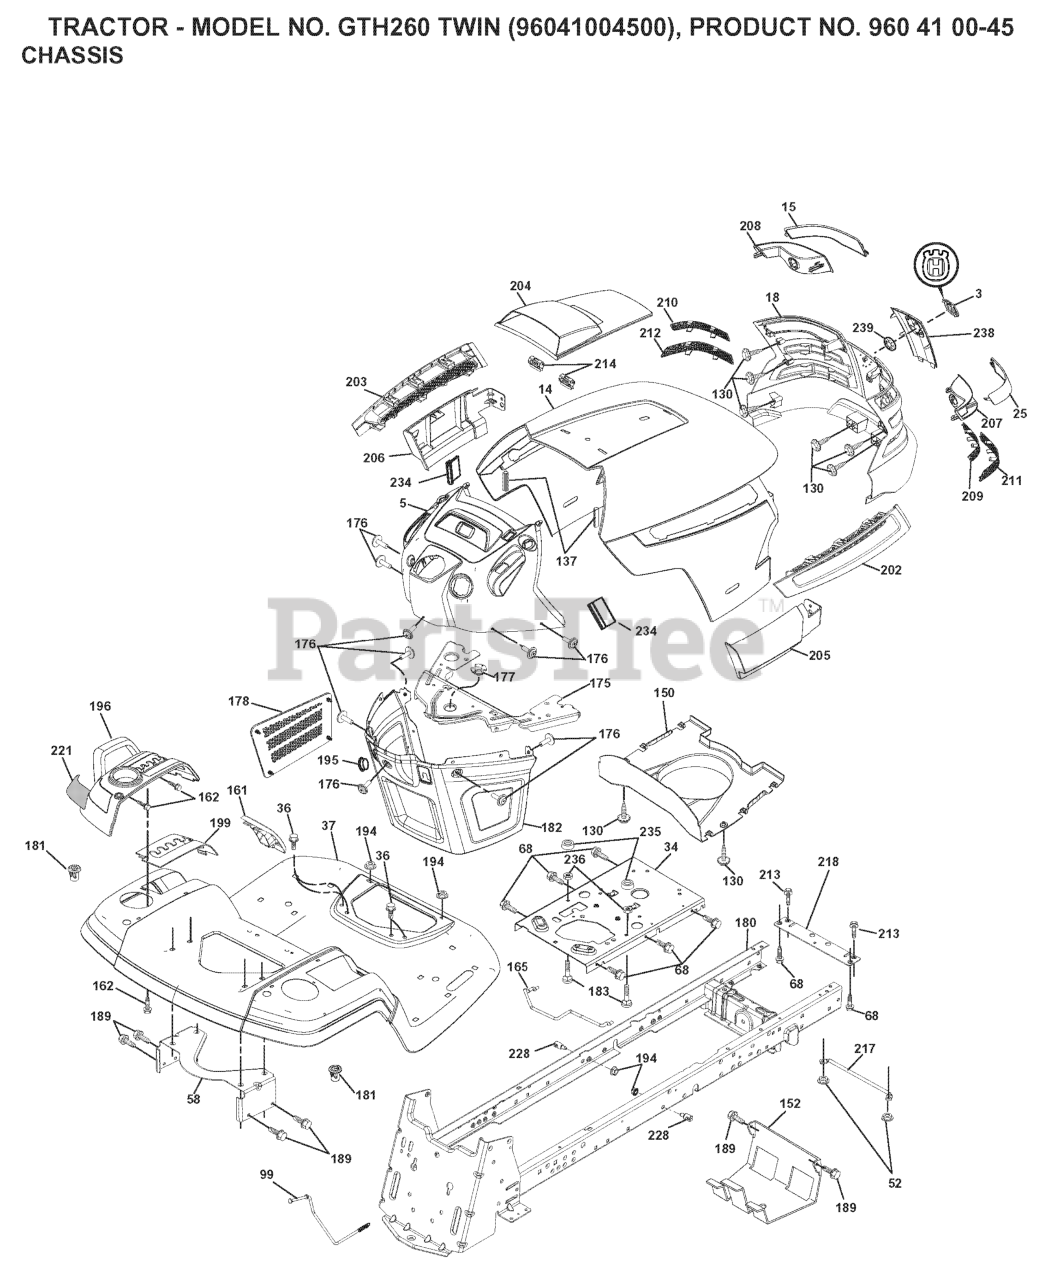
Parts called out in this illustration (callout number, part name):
3	RP LOGO
5	DASH.ASM.HUSQ.GT.E.RECT.W/CK
14	HOOD
15	LENS.LH.TEX.GT.HUSQ.CL
18	GRILL.ASM.HUSQ.TG/CRD.W/TRIM
25	LENS.RH.TEX.GT.HUSQ.CL
34	PLATE.ENGINE.WELDED.CHASSIS
36	SCREW 5/16"
37	FENDER.PNT.TX.GT.CH/FW.ORANGE
52	LOCKNUT
58	BRKT.SUPPORT.FNDR/TANK
68	Screw 5/16-18 x 1/2 Hex, Self Tapping 5/16-18 x 1/2
99	ROD BYPASS ASM.
130	SCREW
137	BUMPER DASH
150	AIR.DUCT.HOOD.TEX.GT.HUSQ
152	SHIELD.BROWNING.W/TEX
161	CONSOLE.FUEL.WINDOW.HU
162	SCREW.HI-LO.CONSOLE
165	SUPPORT.TANK.REAR.W/TEX
175	PLATE.CROSSMEMBER.HUSQ
176	SCREW.#10-24X5/8.RN.QU
177	BUSHING, STEERING
178	CARGO.ASM.NET.TXGT.W/C
180	CHASSIS.GT.SLOPED.DRAWBAR.
181	BUSHING.MNT.FEND.CRGO.
182	DASH.LOWER.COMMON.12V.
183	BOLT.5/16-18X1-1/4 FULL.THREAD
194	NUT LOCK HEX FLANGE 5/16-18
195	PLUG.HOLE.DASH.LOWER.12V.BLK
196	RP CONSOLE.ASM.DECKLFT.W/
199	PLATE.DECK.LIFT.HUSQVARNA.GT
202	VENT.SIDE.HOOD.HUSQ.RH.GREY
203	VENT.SIDE.HOOD.HUSQ.LH.GRAY
204	VENT.TOP.HOOD.HUSQVARN
205	SKIRT.HOOD.SIDE.HUSQ.RH.GREY
206	SKIRT.HOOD.SIDE.HUSQ.LH.GREY
207	BEZEL.RH.TEX.GT.HUSQ
208	BEZEL.LH.TEX.GT.HUSQ
209	INSERT.HEX.GRILL.HUSQ.GREY
210	INSERT.HEX.GRILL.HUSQ.
211	INSERT.HEX.GRILL.HUSQ.
212	INSERT.HEX.GRILL.HUSQ.
213	BOLT
214	CLIP.RETAINER.TINNER.
217	ROD PIVOT CHASSIS/HOOD
218	X-PIECE.HOOD.STOP.NON/
221	REFLECTOR.LH.TEX GT HU
228	STUD.FASTNER.W/ANTI-ROTATE
234	BUMPER.HOOD.TEX.HUSQVARNA
235	SPACER FENDER
236	NUT.CENTERLOCK.5/16-
238	TRIM.HUSQ.TG/CRD.SERVICE
239	NUT PUSH M
